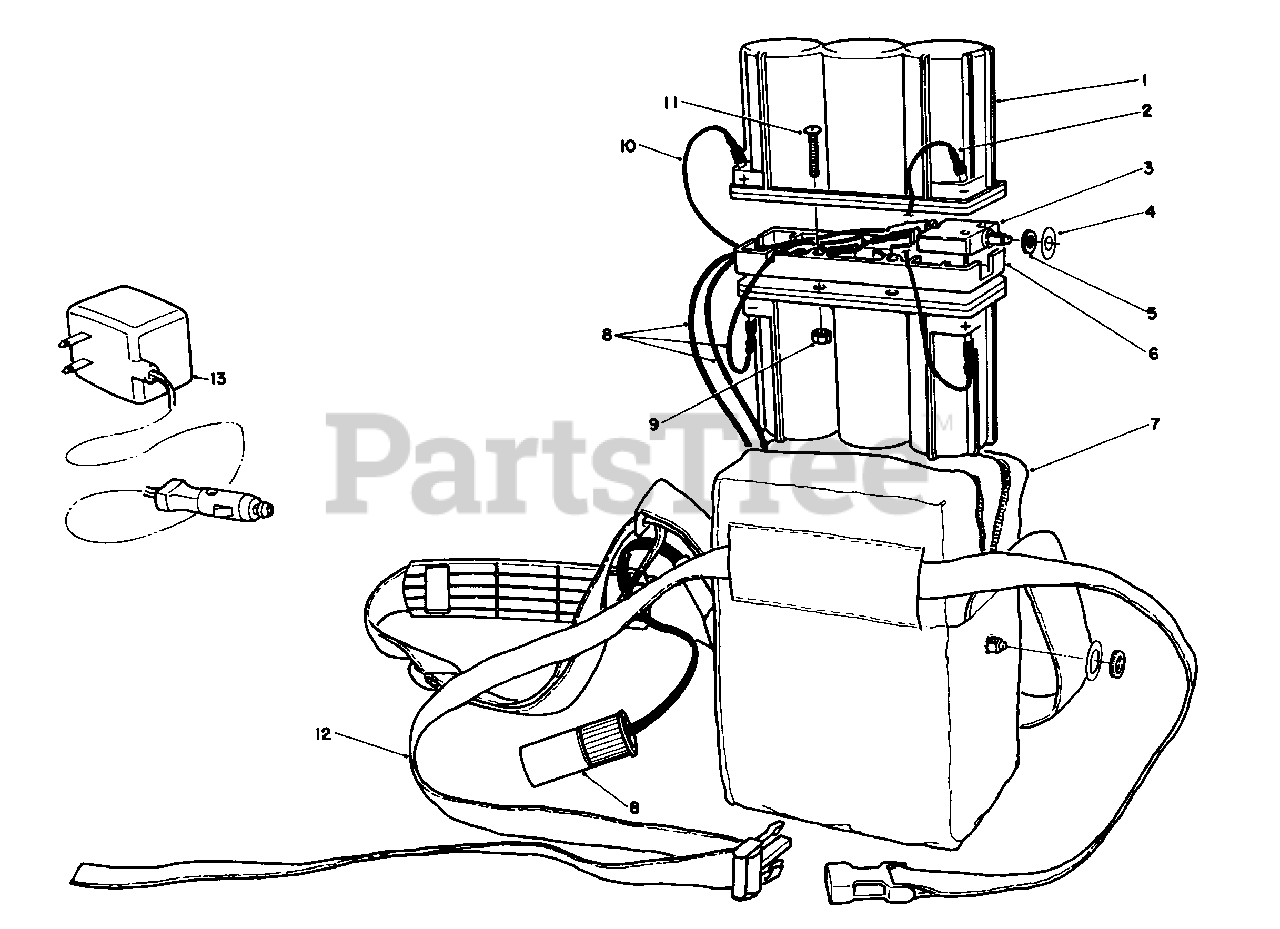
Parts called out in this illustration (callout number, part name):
1	Battery-6 Volt
2	Wire-Battery
3	Circuit Breaker
4	Plate-Breaker, Circuit
5	Nut-Knurled
6	Spacer-Battery
7	Pack-Soft
8	Cord-Battery
10	Wire-Breaker, Circuit
11	Screw-Phillips, Pan Hd.
13	Charger-12 Volt
